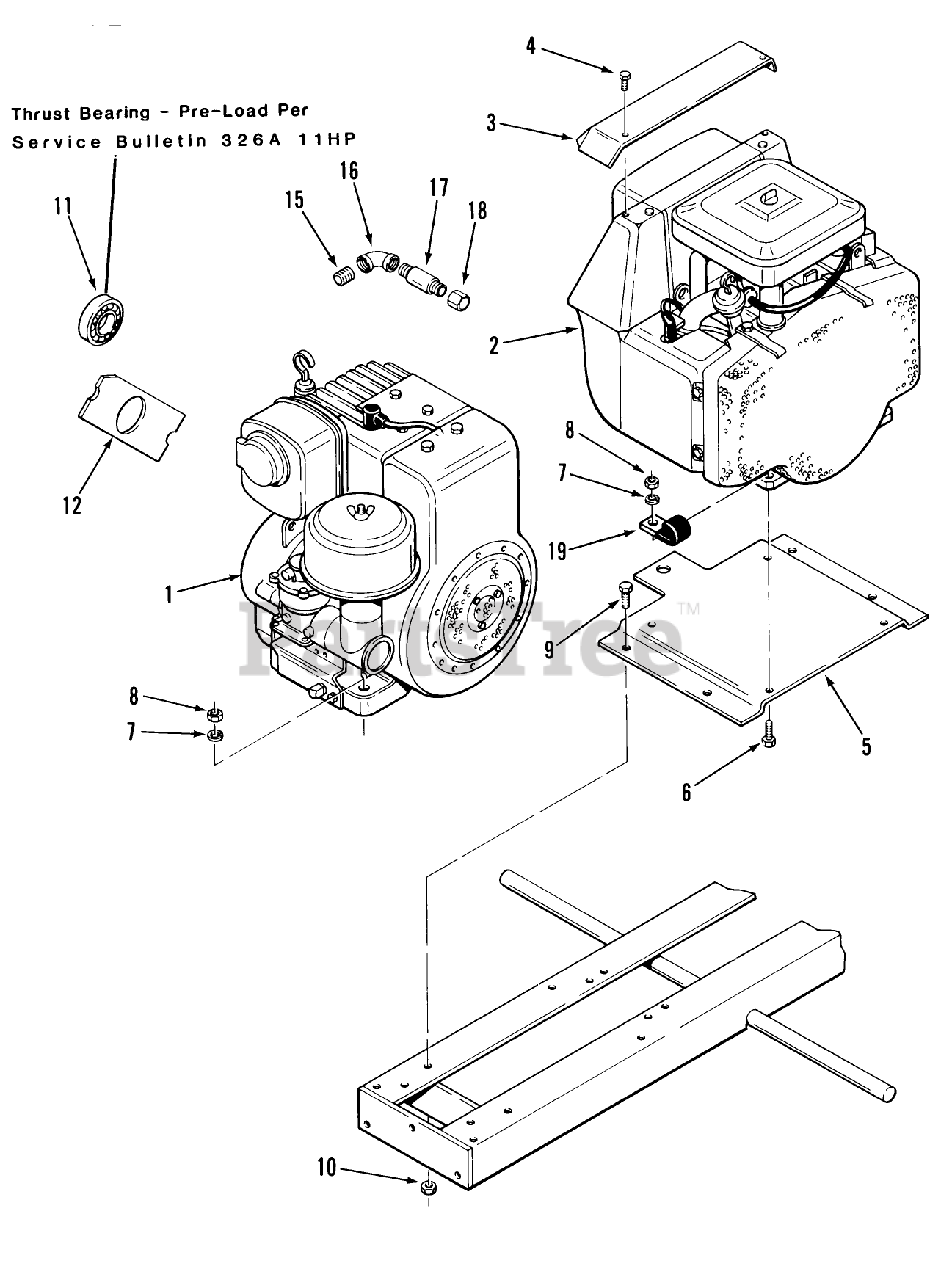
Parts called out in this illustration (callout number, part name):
1	Engine-11HP-BS Model 252417, Type 0664-01
2	Engine-16HP-BS Model 402437, Type 0694-01 GT-1600
2	Engine-18HP-BS Model 422437, Type 0663-01 GT-1800
4	Bolt
5	BASE ENGINE *R
19	CLIP
